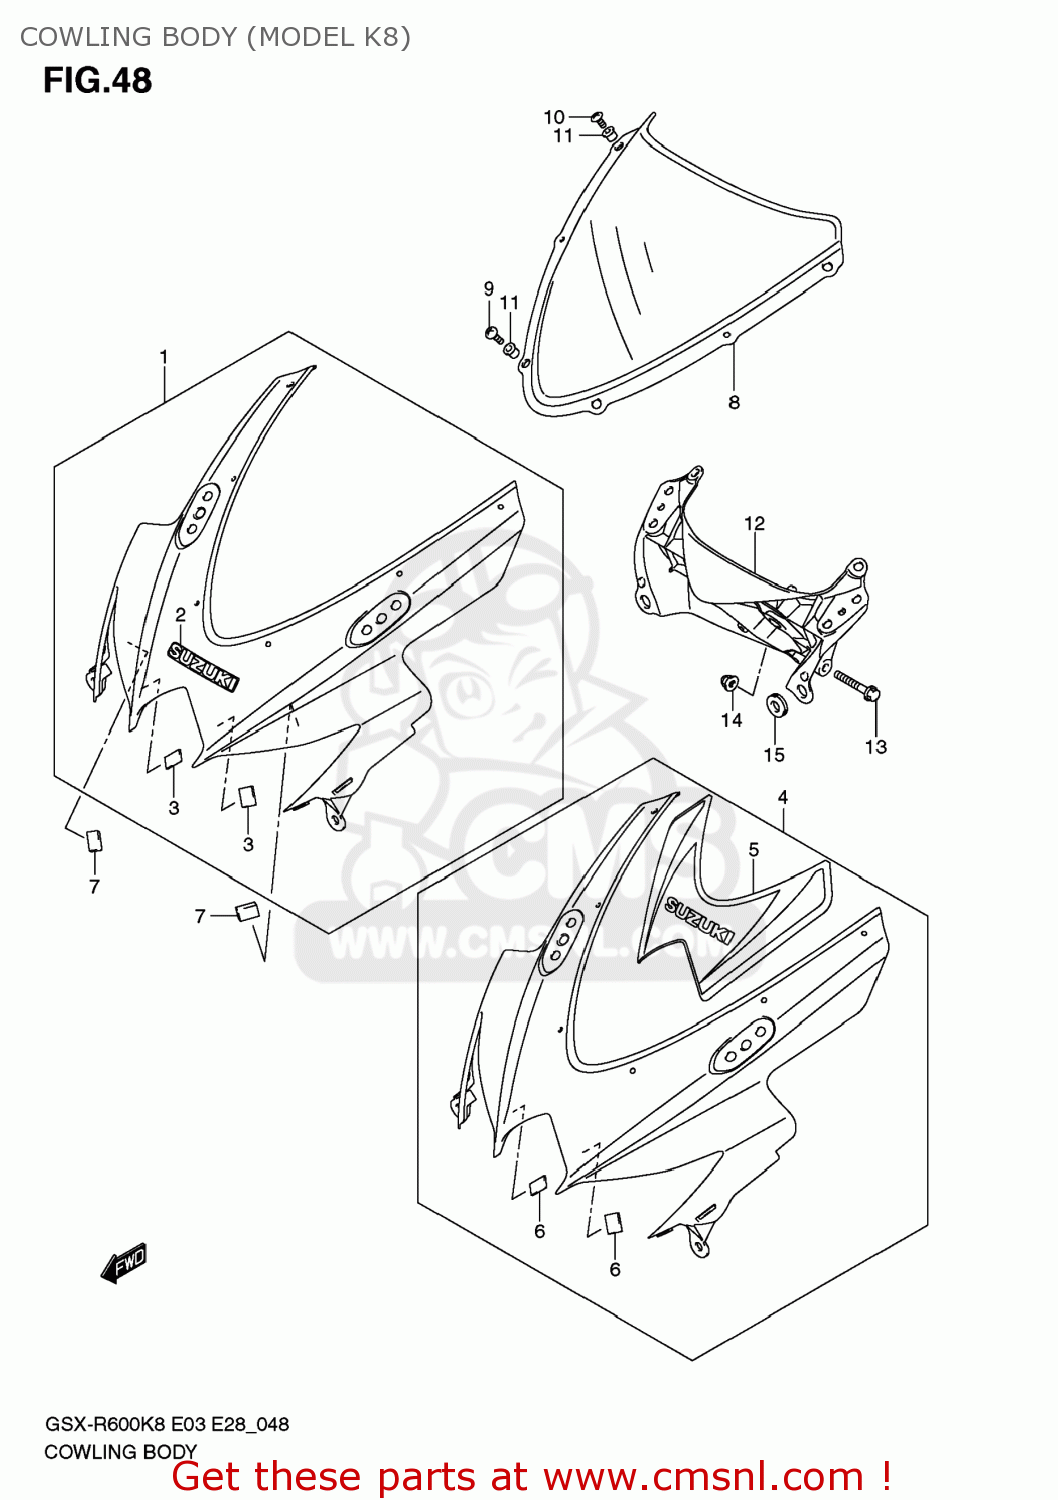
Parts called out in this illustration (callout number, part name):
1	BODY ASSY,COWLING
2	EMBLEM,SUZUKI
3	FASTENER,COWLING
4	BODY ASSY,COWLING
5	TAPE,BODY COWL
6	FASTENER,COWLING
7	CUSHION,BODY COWLING
8	WINDSCREEN
9	SCREW(5X18)
10	SCREW(5X15)
11	NUT
12	BRACE,COWLING
13	BOLT
14	NUT
15	CUSHION
